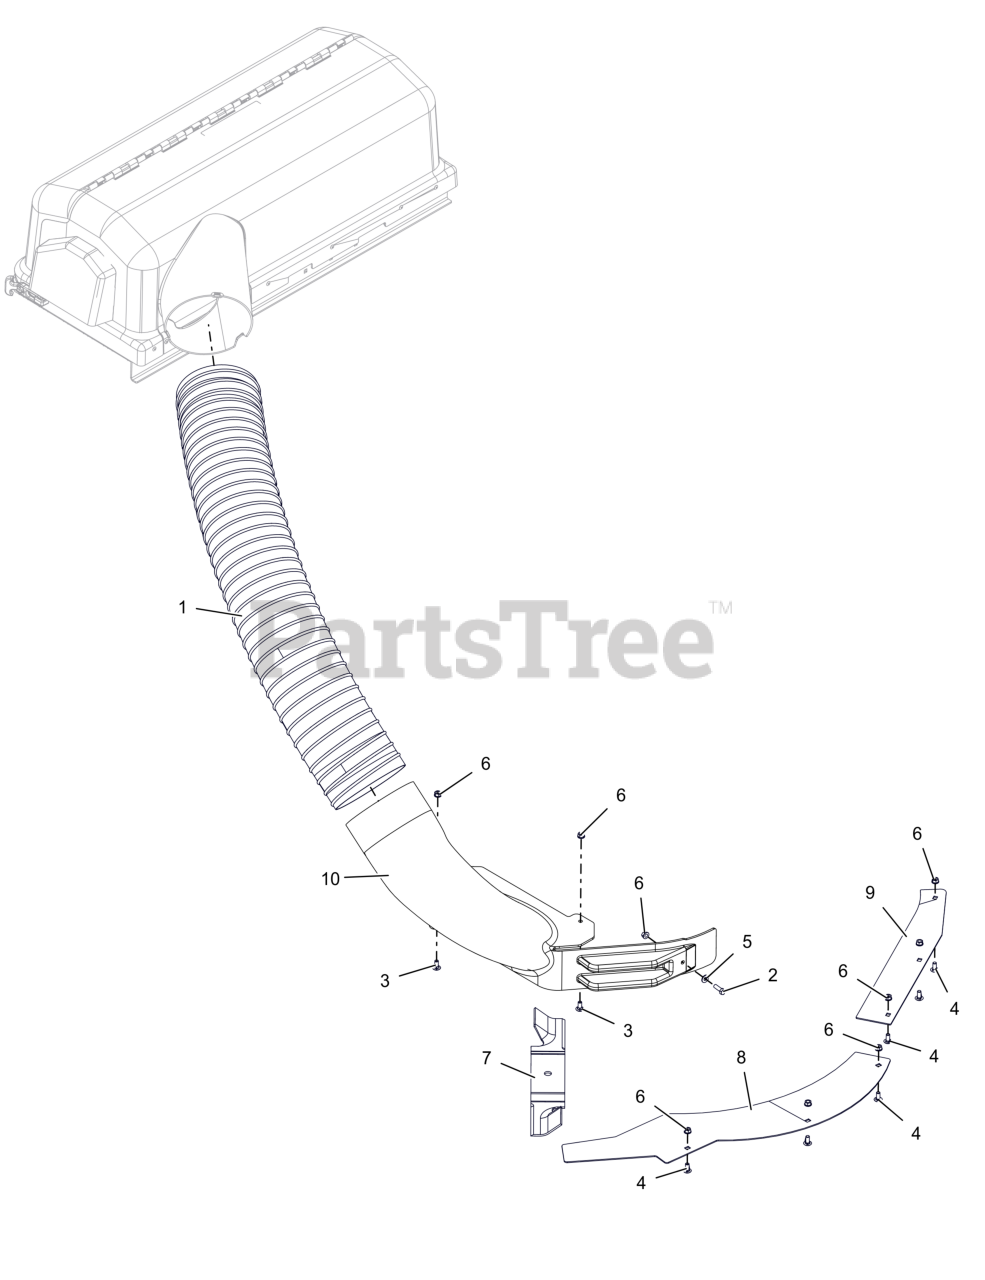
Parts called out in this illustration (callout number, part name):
1	HOSE, FLEXIBLE-47"
2	BLT,HEX .31-18X1.00 G5 ZCC
3	BLT,RHSN .31-18X.75 G5 ZCC
4	BLT, RHSSN.31-18X.750 G5 ZCC
5	WSHR, FLT .312X.734X.065 ZCC
6	NUT,LK-CTR-FLG .31-18 GF ZCC
7	BLADE, MOWER - 18"
8	BAFFLE, BAGGER (BLACK)
9	BAFFLE, BAGGER (BLACK)
10	NECK, BAGGER - 52" DECK
